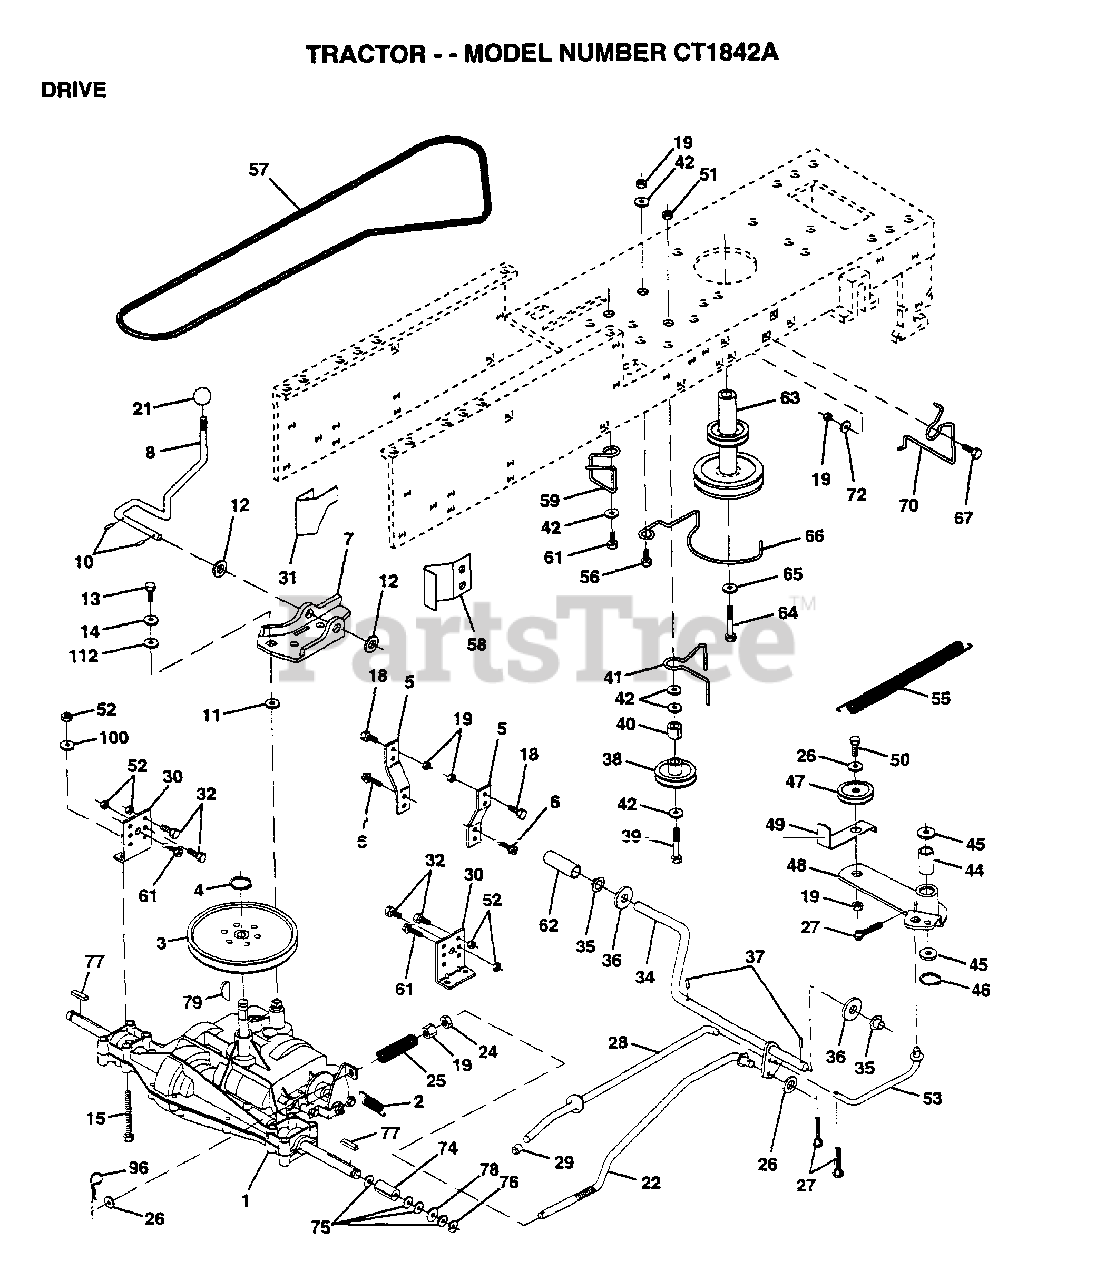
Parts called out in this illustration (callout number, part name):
2	SPRING.BRAKE.RETU
3	PULLEY TRANS
5	STRAP TORQUE
6	SCREW
8	SHIFT ROD
10	PIN COTTER 1/8
11	WASH-SHFT PLT LT
12	WASHER
13	BOLT.1/4-28.W/PAT
14	LOCKWASHER
15	BOLT HEX
18	BOLT
19	NUT
21	KNOB T (1/2-HOLE)
22	BRAKE ROD
24	NUT
25	SPRING ROD LT
26	WASHER
27	COTTER PIN
28	ROD.BRAKE.PARK.LT
29	PLUNGER CAP T
30	TRANSAXLE MTG BKT
31	"KEEPER,BELT LH T"
32	BOLT
35	NYLON BEARING
36	WASHER LT
38	PULLEY.IDLER.FLAT
39	BOLT
40	SPACER T
41	BELT KEEPER LT
42	WASHER
44	"LY, BEARING"
45	WASHER LT
46	KLIP RING
48	ARM IDLER
49	RETAIN BELT
53	"LINK, CLUTCH T"
55	"SPRING, RETURN LT"
58	"KEEPER,BELT RH T"
59	KEEPER BELT CNTSP
61	SCREW
62	PEDAL COVER T
63	PULLEY.ENGINE
64	BOLT
65	LOCKWASHER
66	KEEPER.BELT.ENG.L
67	BOLT
70	KEEPER BELT ENG
72	WASHER
74	SPACER AXLE
75	WASHER
76	E-RING LT
77	SQUARE KEY
78	WASHER
96	RETAINER M
100	WASHER M
112	WASHER LT
